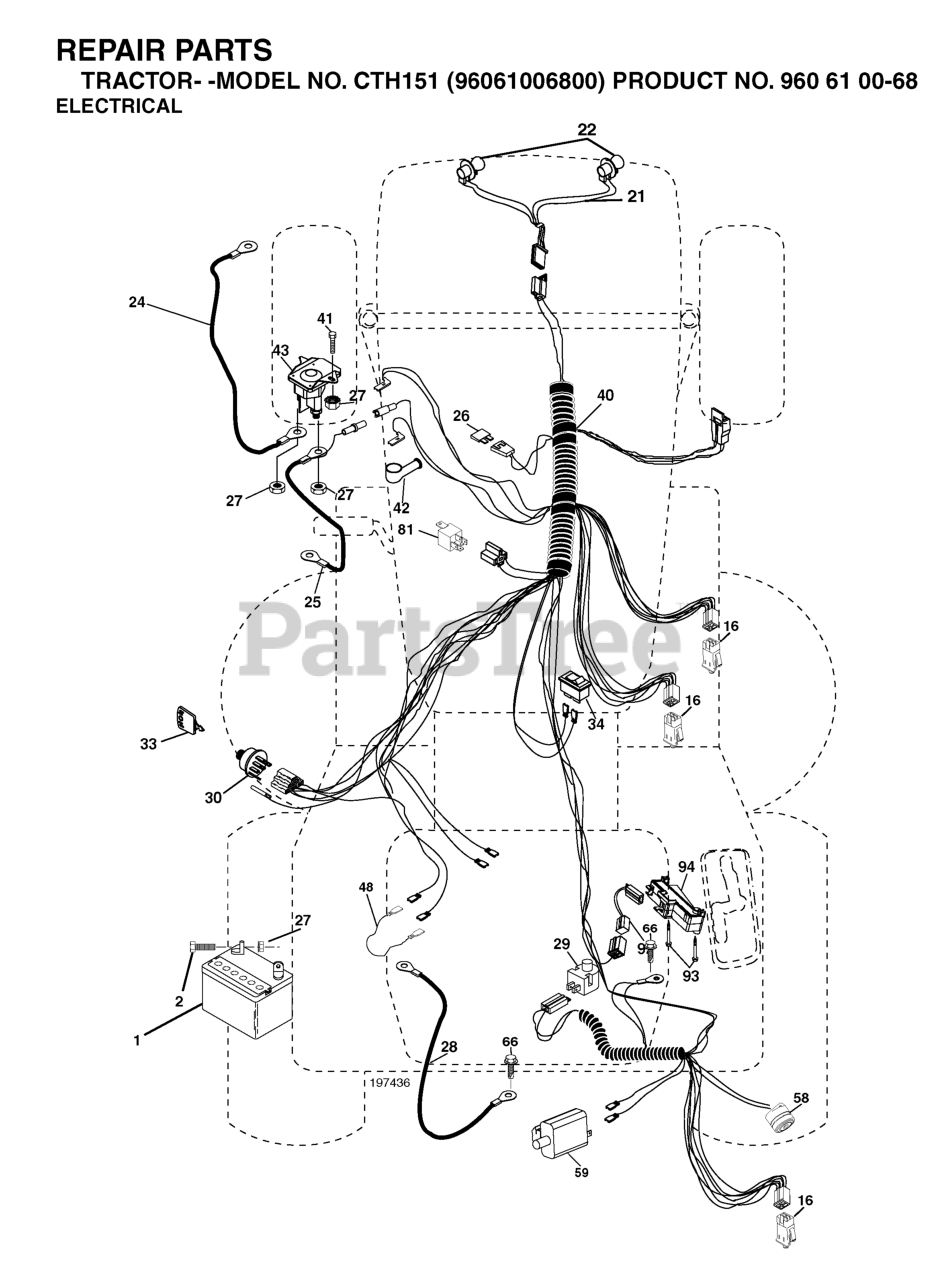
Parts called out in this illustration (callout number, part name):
1	BATTERY 12V .35 AMP
2	BOLT.HEX.1/4.X.3/4.DICHROMATE
16	SWITCH INTERLOOK PUSH-IN
21	HARNESS.W/LIGHT SOCKET
24	BATTERY CABLE GT
25	CABLE BATTERY
26	FUSE 20AMP
27	NUT
28	CABLE GROUND
29	SWITCH.SEAT.DP W/RAMPS
30	SWITCH.IGN.DELTA.W.LGH.ROS
33	KEY MLD GEN DELTA
41	BOLT
42	TERMINAL COVER
43	SOLENOID.W/BRASS.PLUNGER
48	ADAPTER.AMMETER
58	BUZZER
59	.WITCH.FULL BAGGER.INDICATOR
66	SCREW LT
81	RELAY.ASSY.T
92	HARNESS.PIGTAIL.CONSLE
93	SCREW.PLASTITE
94	MODULE.REVERSE.ROS
